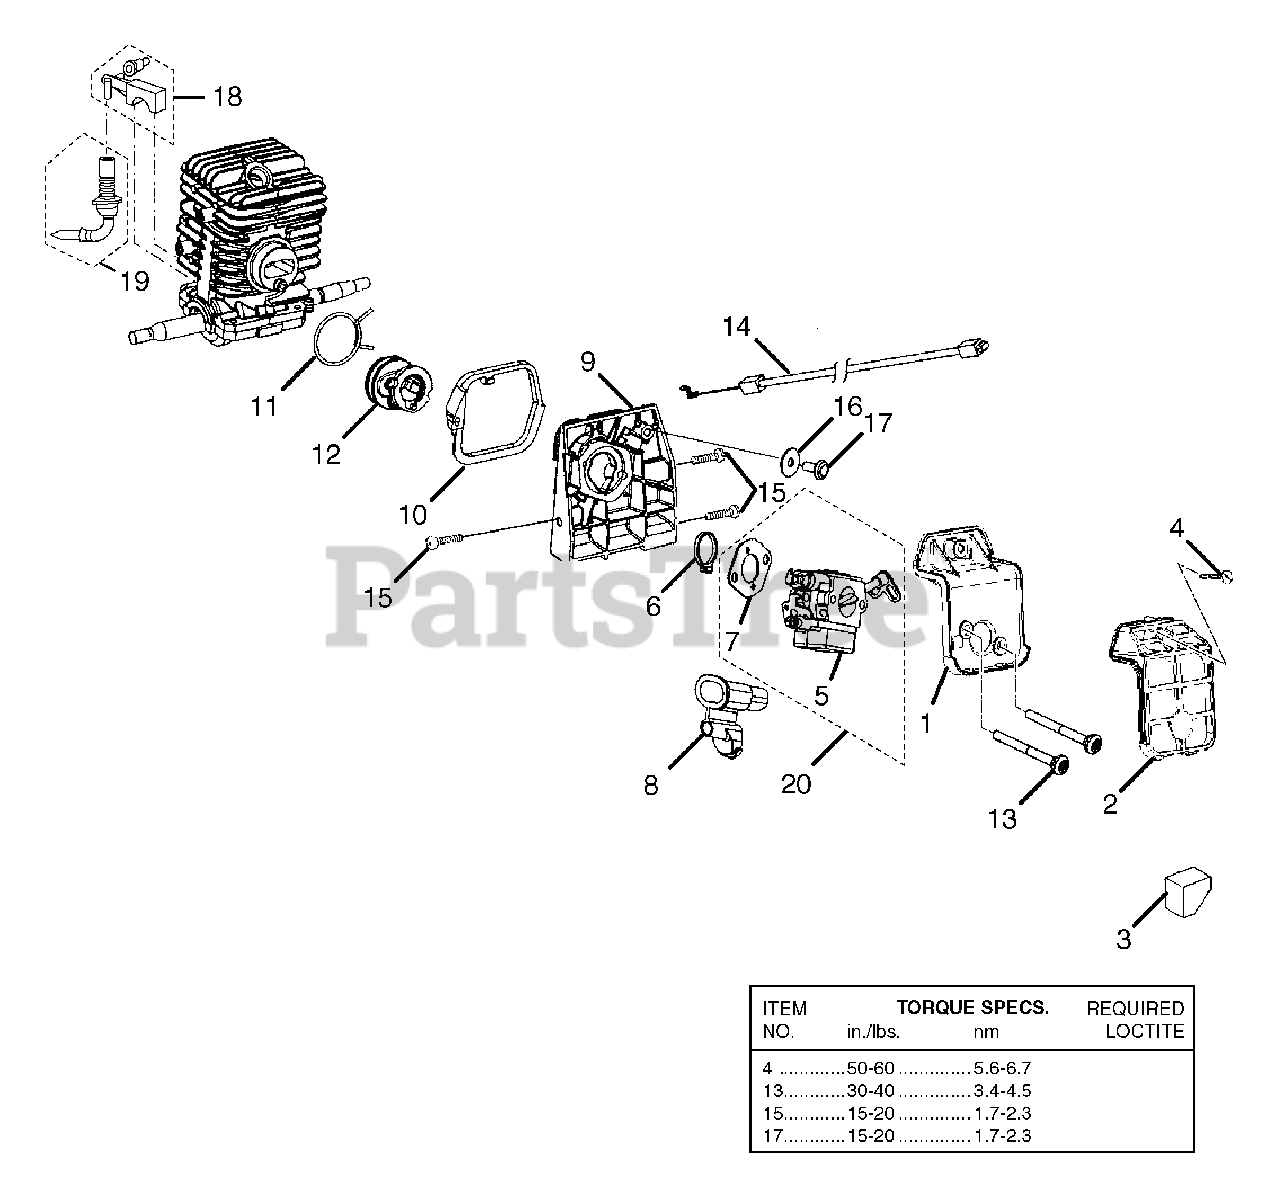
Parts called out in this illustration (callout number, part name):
1	AIR FILTER BASE
2	AIR FILTER COVER
3	PRE FILTER (IN ENGINE HOUSING)
4	SCREW (8-16 x 5/8 in.)
5	CARBURETOR
6	PLATE, CARBURETOR
7	GASKET, CARBURETOR
8	GROMMET, CARBURETOR
9	ADAPTOR, CARBURETOR
10	SEAL-CARB. ADAPTOR
12	INTAKE BOOT
13	SCREW (10-32 x 1.75 mm)
14	THROTTLE CABLE
15	SCREW (TORX)
17	SCREW
18	OIL PUMP ASSEMBLY
19	OIL INTAKE W/FILTER
20	CARBURETOR ASSEMBLY
